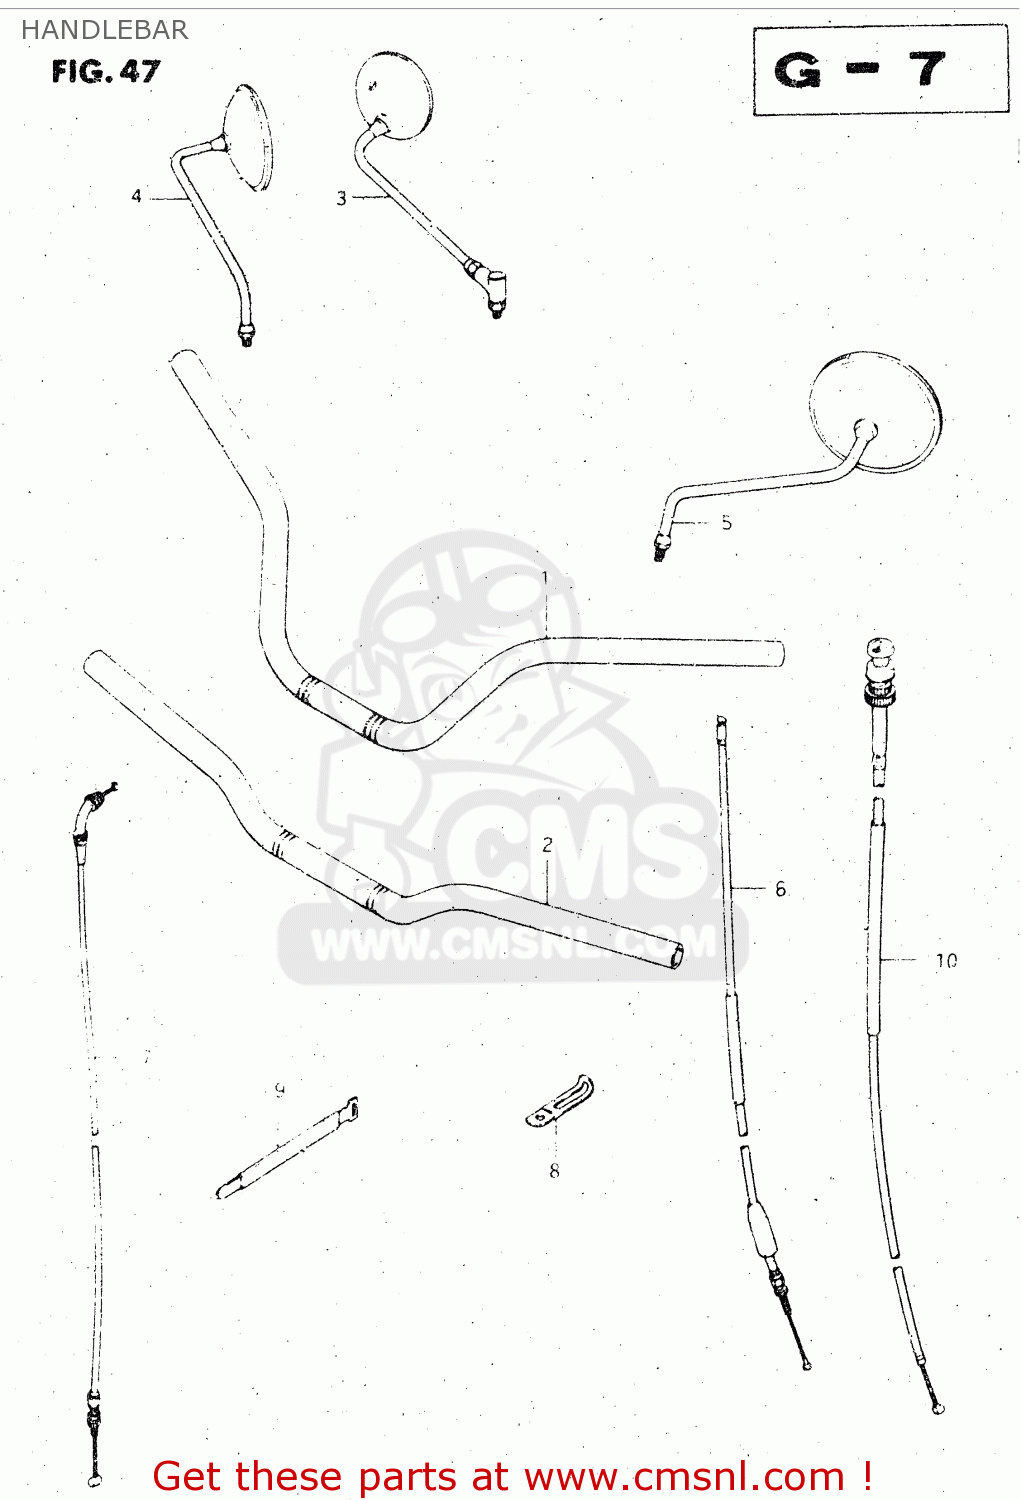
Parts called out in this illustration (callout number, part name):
1	HANDLEBAR (NERTRAL)
2	HANDLEBAR (FLAT)
3	MIRROR ASSY,RH
4	MIRROR ASSEMBLY,REAR VIEW
5	MIRROR ASSEMBLY,REAR VIEW
6	CABLE ASSY,CLUTCH
7	CABLE ASSEMBLY,THROTTLE
8	CLAMP
9	CLAMP
10	CABLE ASSEMBLY,STARTER
